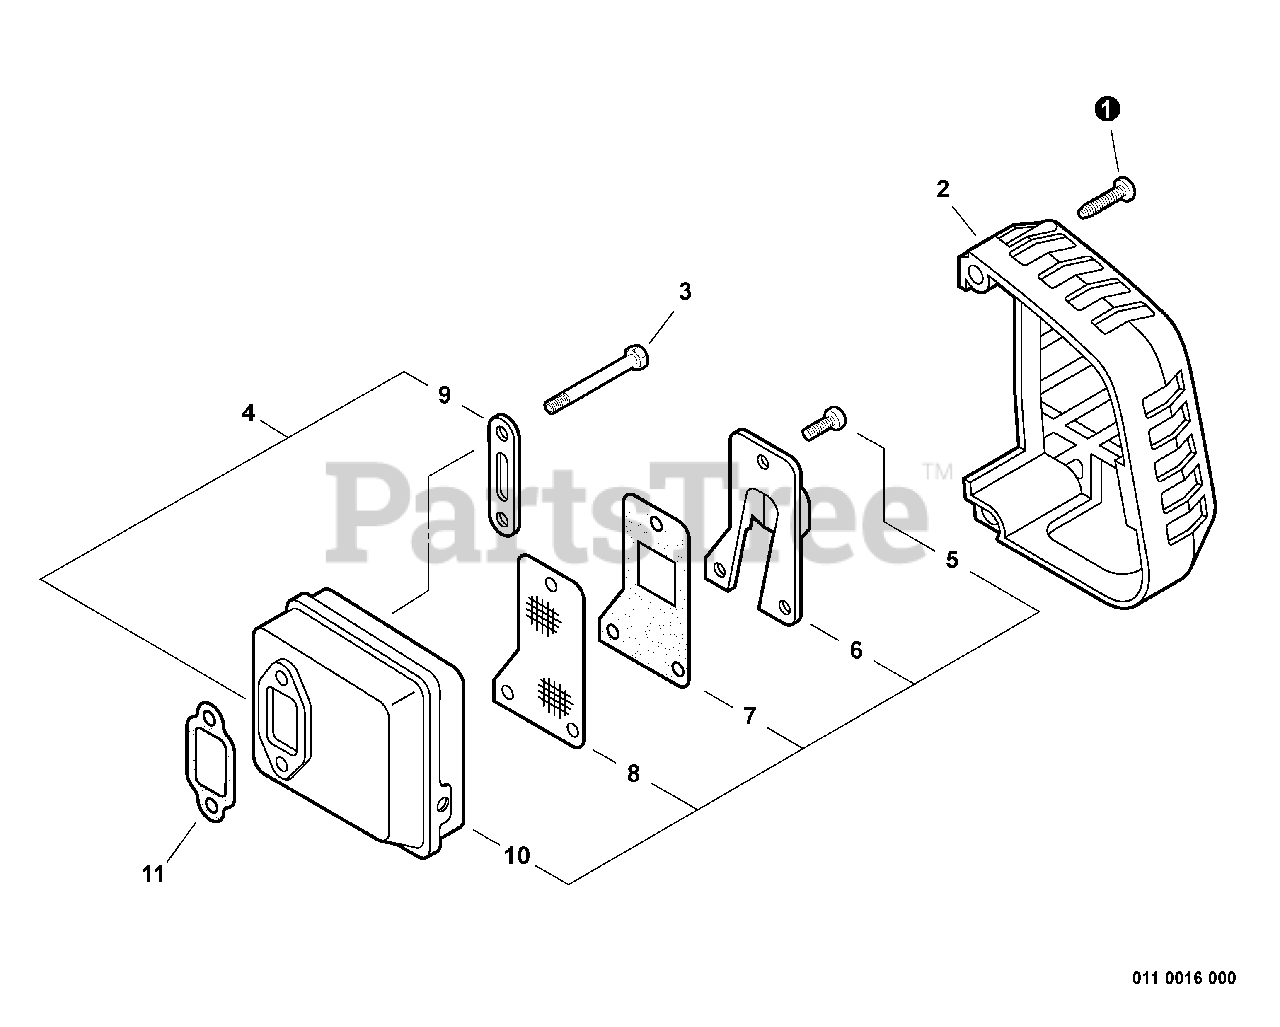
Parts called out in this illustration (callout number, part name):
1	SCREW, TAPPING 5×20
2	COVER, MUFFLER
3	BOLT 6 MM
4	MUFFLER ASSY
5	SCREW 4
6	COVER, MUFFLER
7	GASKET, EXHAUST
8	SCREEN, SPARK ARRESTER
9	PLATE, MUFFLER
10	MUFFLER
11	GASKET, MUFFLER
